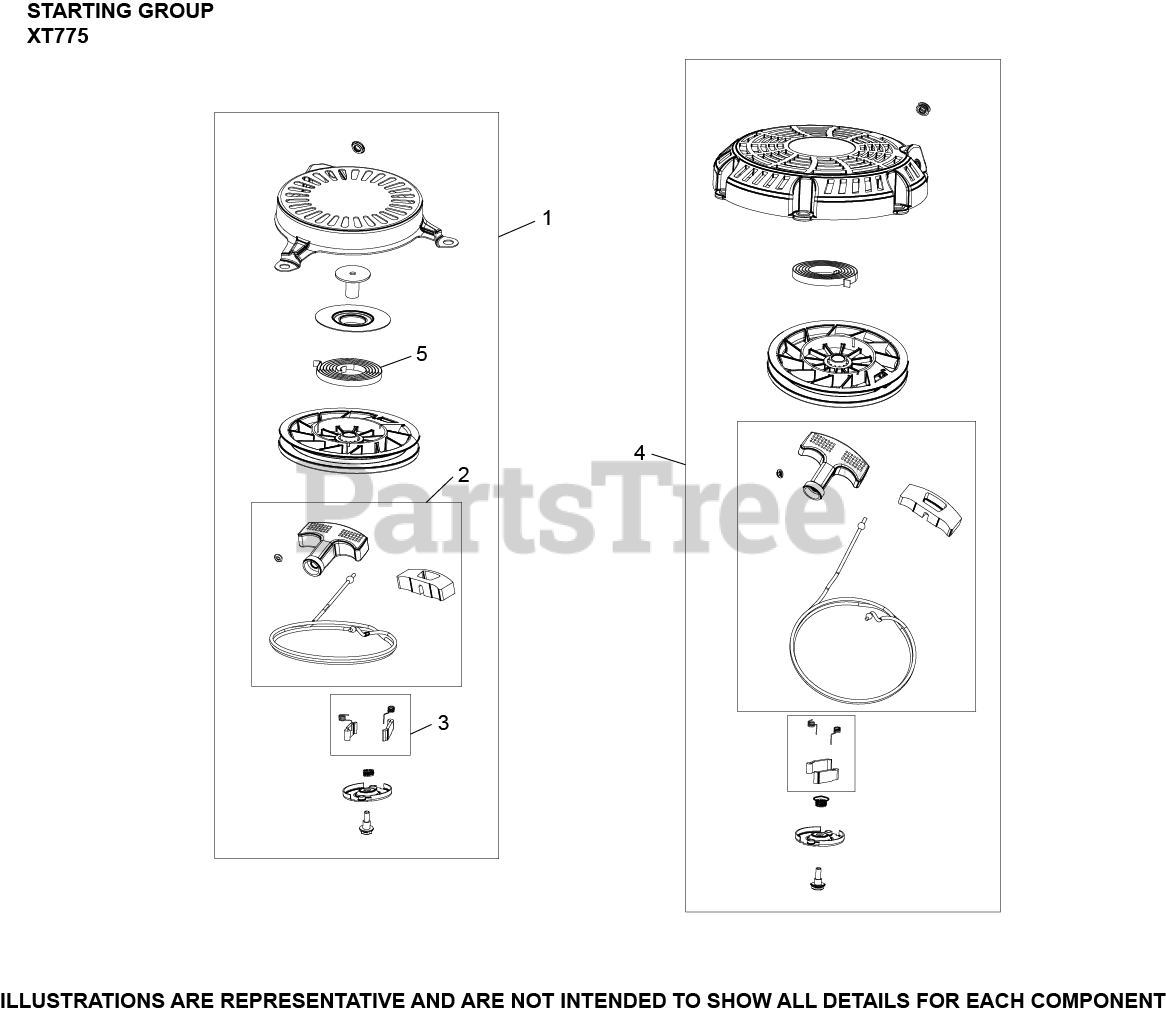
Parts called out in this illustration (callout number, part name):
2	ROPE, RECOIL STARTER
3	KIT, PAWL REPAIR
4	STARTER ASSEMBLY, RETRACTABLE
